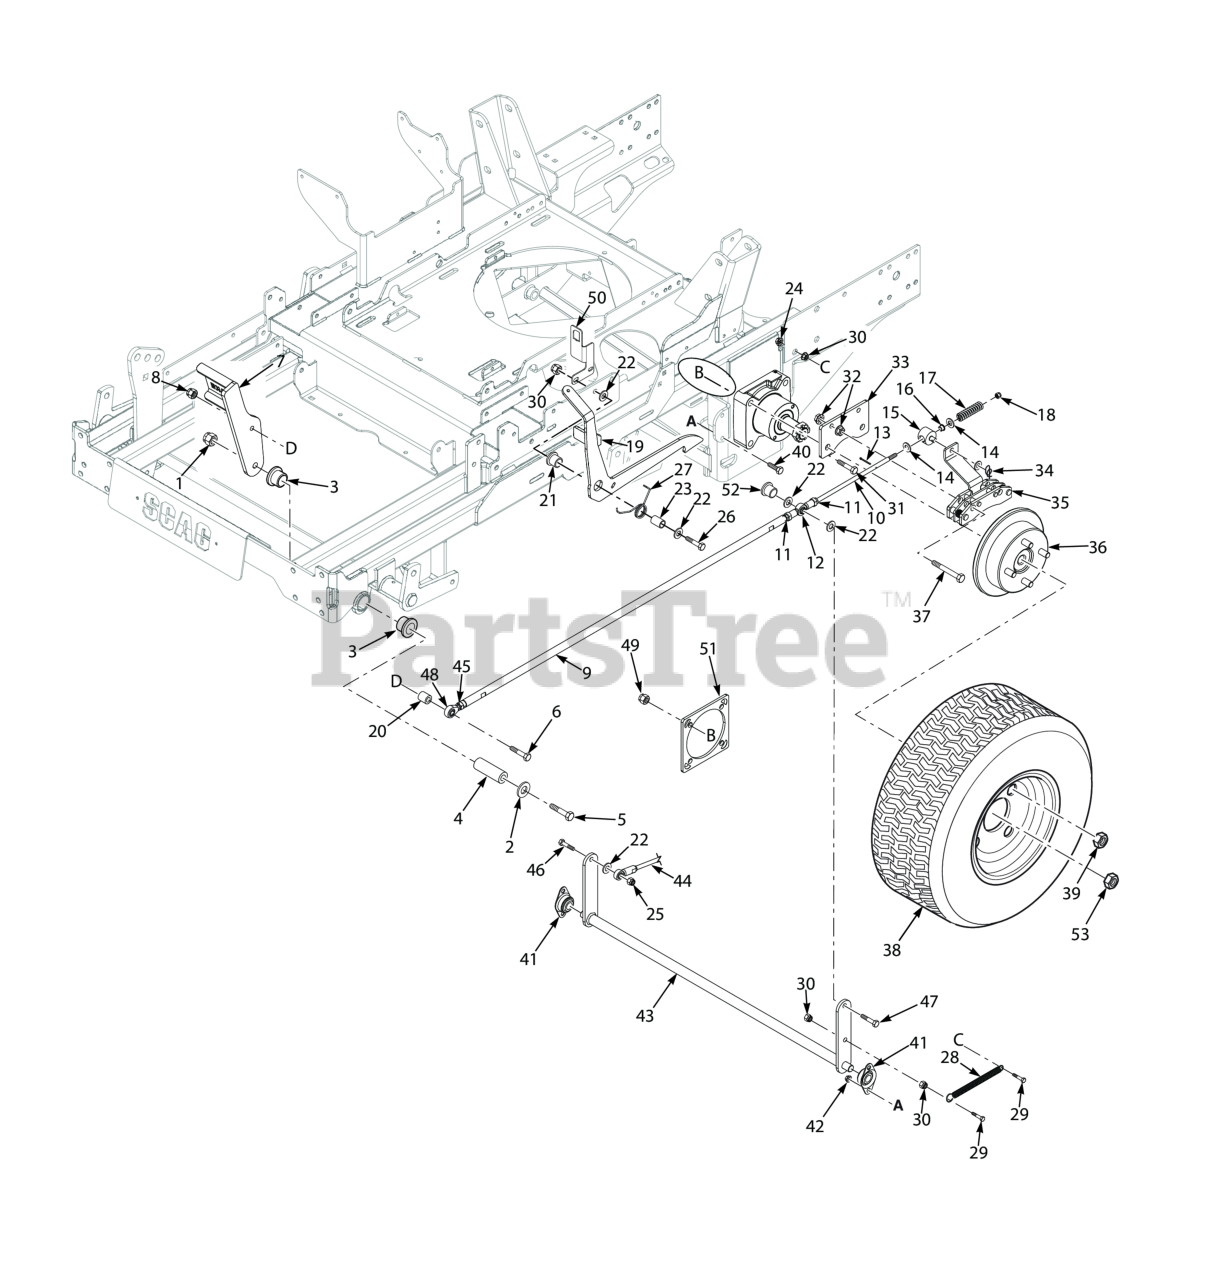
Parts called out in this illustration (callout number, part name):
1	HEX LOCKNUT, ELASTIC STOP, 1/2-13
2	Flat Washer, 1/2 (.562 x 1.375 x .109)
3	Bearing, Plastic
4	Sleeve, Brake Pivot
5	Bolt, Hex Head 1/2-13 x 4-1/4"
6	Capscrew, Hex Head 3/8-16 x 2.75"
7	Foot Pedal, Brake
8	HEX NUT, ELASTIC STOP LOCK, 3/8-16
9	Link, Brake
10	Linkage Assy., LH Brake (incl. #9, 11 - 18,45,48)
11	Nut, 3/8-24 UNF R.H. Thread
12	Rod End w/Trunion
13	Pin, Cotter 3/32 x .75"
14	Flatwasher, 3/8 (.406 x .812 x .065)
15	Swivel Assembly, Brake
16	Bearing
17	Spring, Brake
18	Nut, Elastic Stop 3/8-16, grade 8 black
19	Brake Handle w/Grip (includes #21)
20	Yoke, Front Caster Wheel
21	Bearing, .625 ID Plastic
22	Flatwasher, 3/8" Special (.391 x .938 x .105)
23	Pivot, Brake Lever
24	Threaded Insert, 3/8-16
25	Bolt, Hex Head 3/8-16 x 1" Ser. Flg.
26	Capscrew, Hex Head 3/8-16 x 2-1/2"
27	Spring, Torsion, Brake Handle
28	Spring, Brake Return
29	Bolt, Hex Head 3/8-16 x 1-1/2" Grade 8 Black
30	NUT, 3/8-16 SERRATED FLANGE HEX HEAD
31	Bolt, Hex Head 1/2-13 x 2-3/4" (48V & 52V - One Weight)
32	Nut, Hex Serrated Flange 1/2-13
33	Mounting Bracket, Brake
34	Pin, Rue Cotter 3/8" Diameter
35	Brake Caliper
36	Wheel Hub w/Disc
37	Bolt, Hex Head 1/2-13 x 4" (lower)
38	Wheel Assy., 26 x 12-12 (61V & 72V)
39	Wheel Nut, 1/2-20 x 13/16
40	BOLT, SERRATED FLANGE HEX HEAD 5/16-18 X 3/4"
41	Bearing, Self Aligning - 5/8 I.D.
42	HEX NUT, ELASTIC STOP LOCK, 5/16-18
43	Bellcrank Weldment, Brake Actuator
44	Linkage Assy., RH Brake
45	Nut, 3/8-24 UNF-2B LH Thread
46	Bolt, Hex Head 3/8-16 x 1-1/4", Kawasaki FX / FT & FT-EFI
47	Bolt, Hex Head w/ Patch 3/8-16 x 1-3/4"
48	Rod End, Male - RH, 3/8-24 Thread
49	Locknut, Hex 1/2-13 Center Lock
50	Bracket, Brake Switch
51	Plate Weldment, Motor Backing
52	Bushing, Brake
53	Nut, Hex Castle 1.0-20 UNEF
